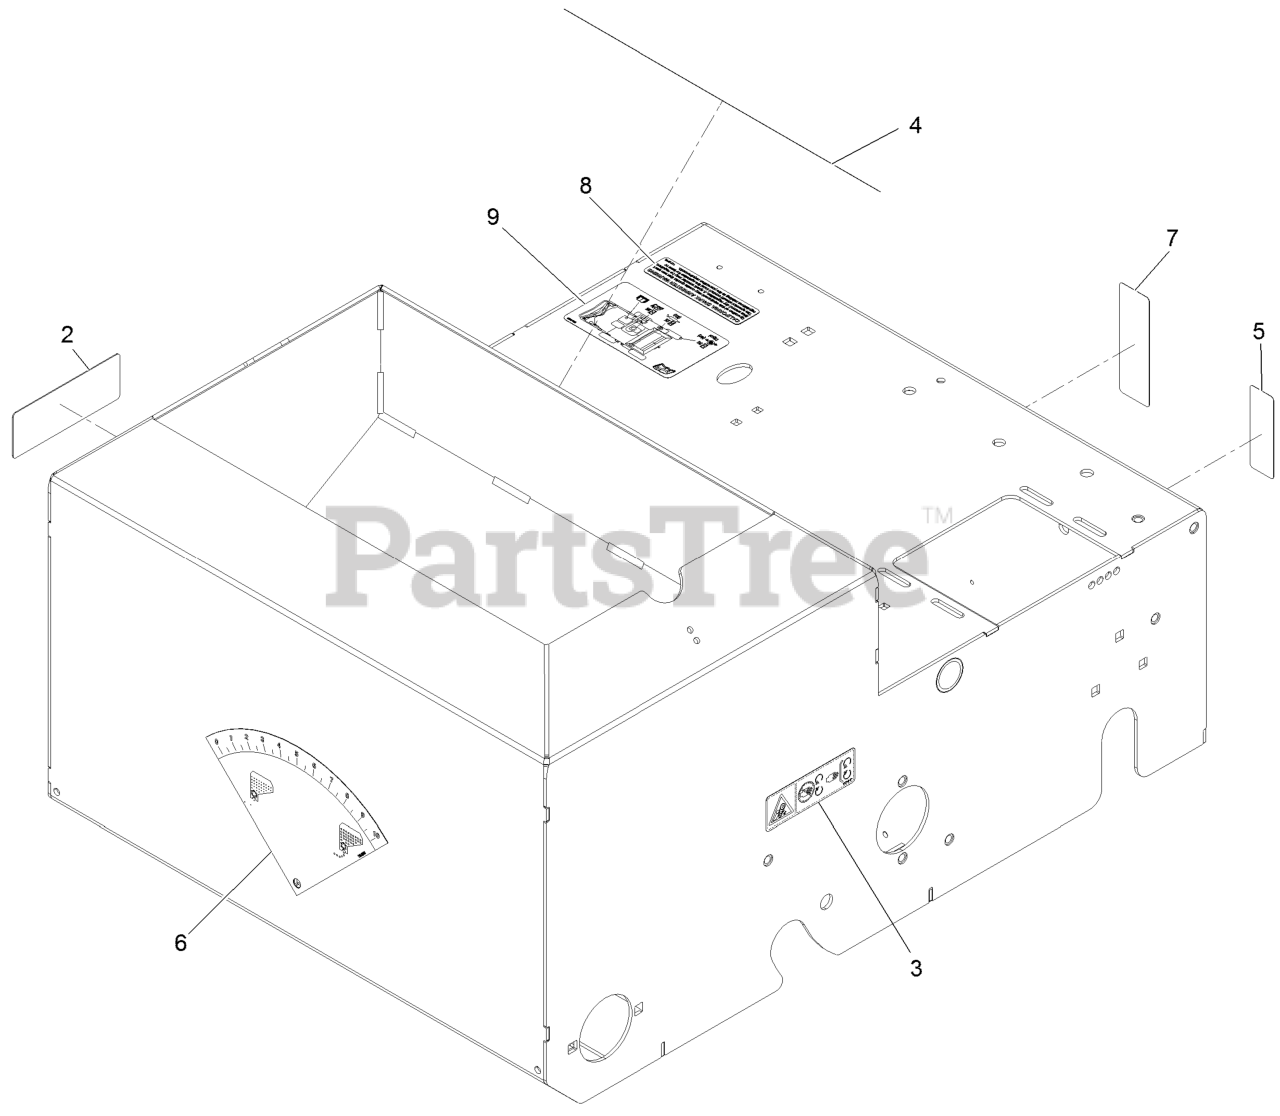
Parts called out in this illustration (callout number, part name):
2	DECAL-DANGER
3	DECAL-WARNING
4	DECAL-WARNING
5	DECAL-BRAKE, PARKING
6	DECAL-FLOW, SEED
7	DECAL-BYPASS
8	DECAL-ARRESTER, SPARK
9	Decal-Service Aid Seeder
